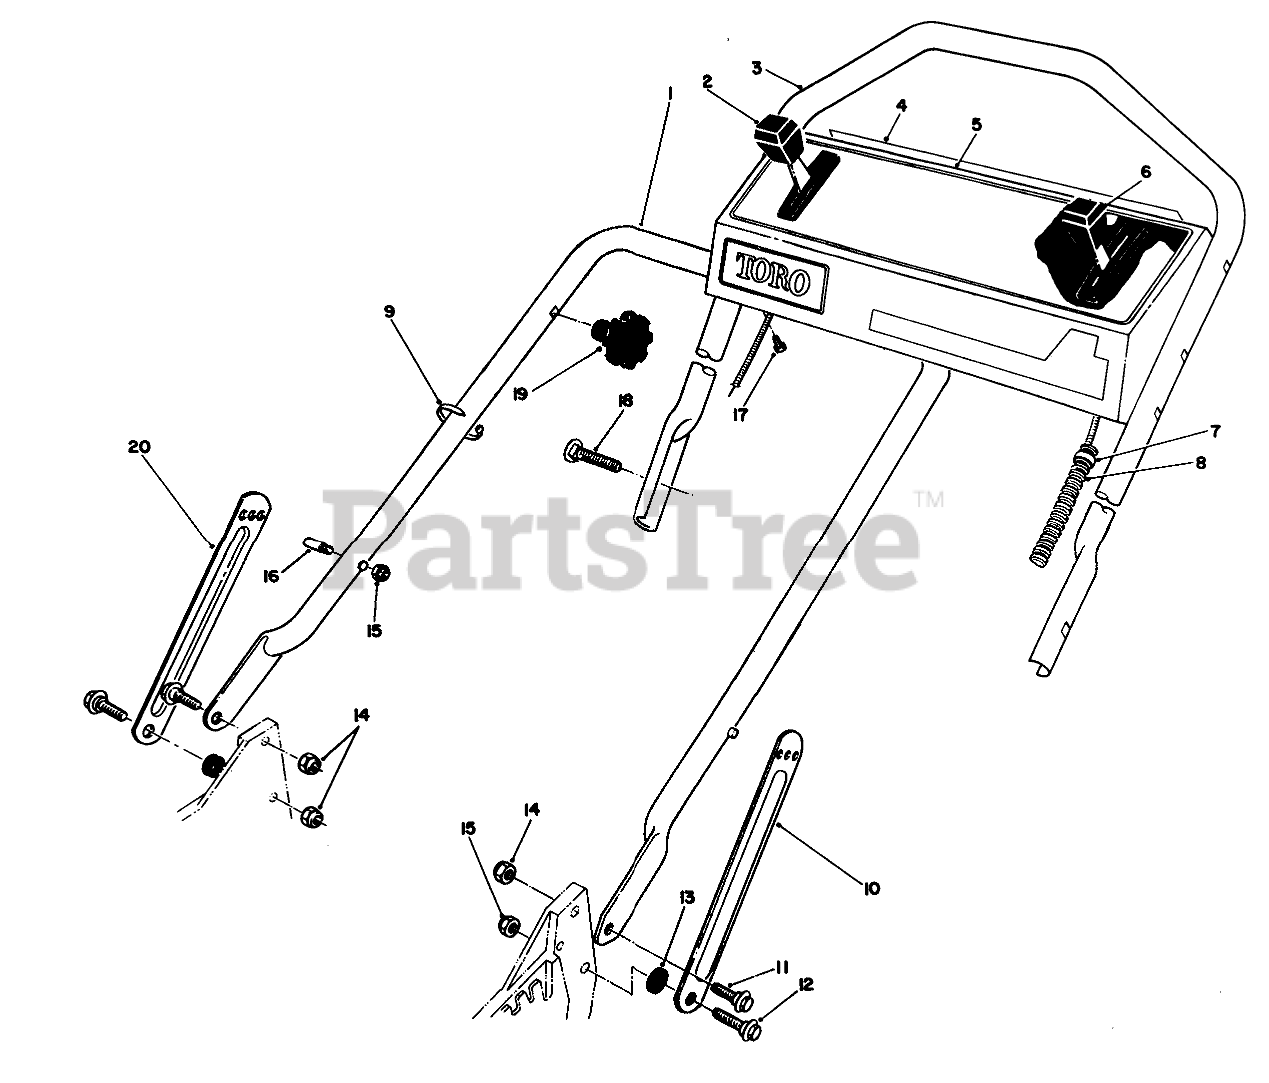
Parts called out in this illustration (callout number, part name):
1	LOWER HANDLE ASM
2	Control-Ground Speed
3	UPPER HANDLE
4	DECAL-PANEL, DANGER
5	Panel-Control (Incl. Ref. #4)
6	THROTTLE CONTROL
7	FITTING-RING
8	CONTROL CABLE COVER
9	TIE-CABLE
10	LH HANDLE LATCH
11	SCREW-SHOULDER
12	SCREW-SHOULDER
13	SPACER
14	NUT-LOCK, NI
15	NUT-LOCK, NI
16	HANDLE PIN
17	SCREW-HWHTF
18	5/16-18 X 2 HNDLE SCREW
20	RH HANDLE LATCH
